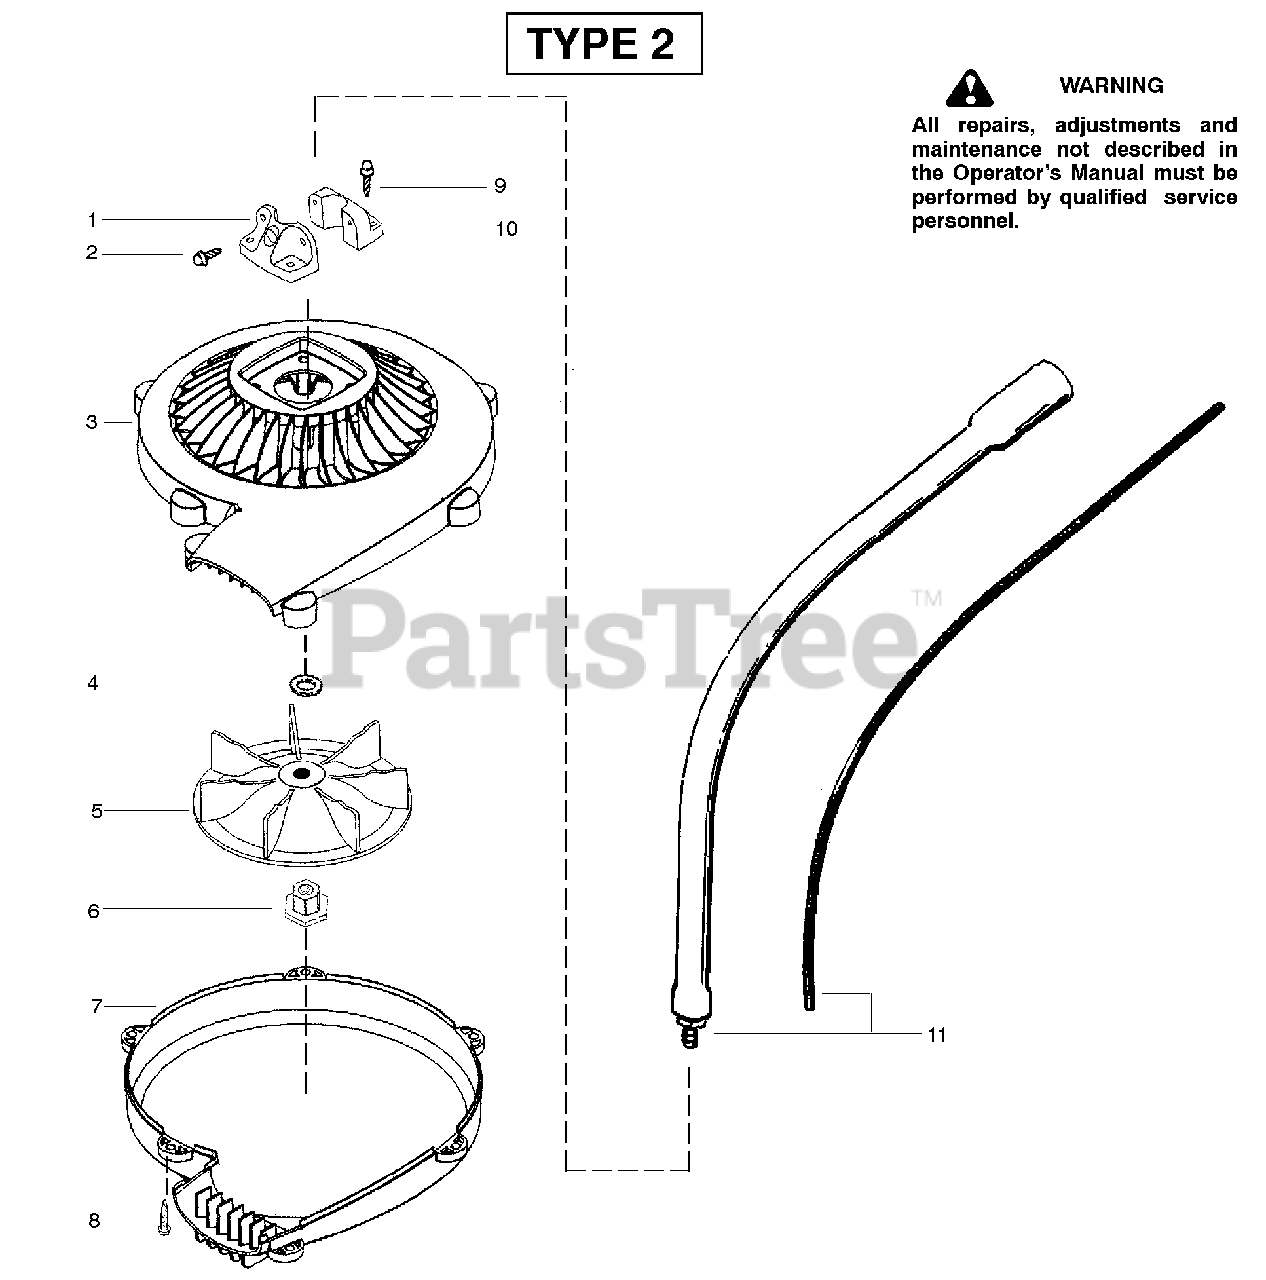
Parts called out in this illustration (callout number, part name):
3	Hsg.-Blower (upper)
6	Arbor-Impeller
7	Hsg.-Blower (lower)
11	Assy-Lower Driveshaft
